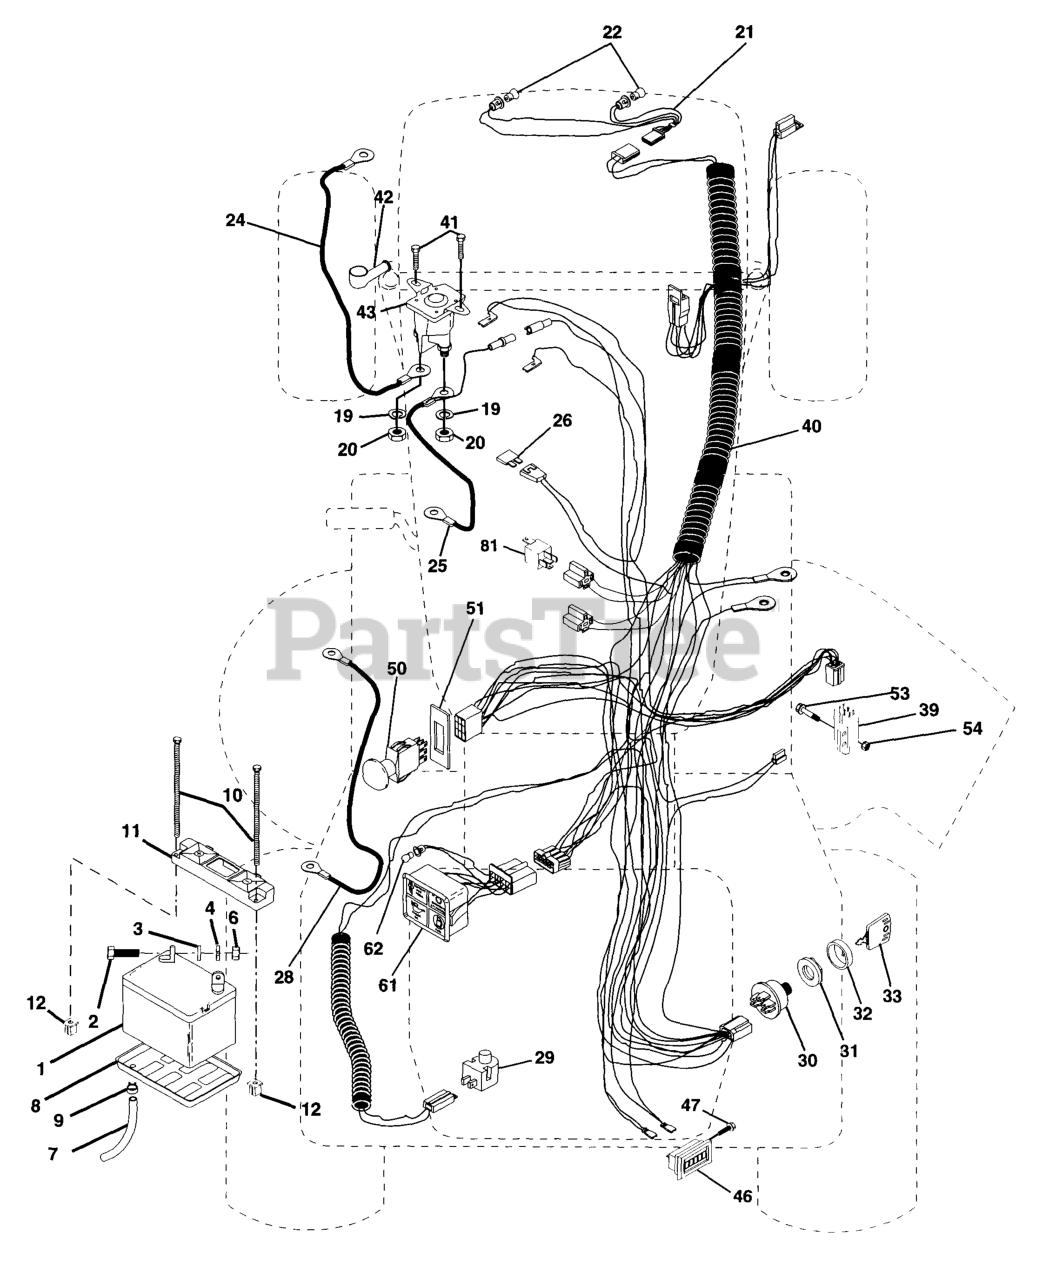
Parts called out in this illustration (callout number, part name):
1	BATTERY
2	BOLT.HEX.1/4.X.3/4.DICHROMATE
3	LOCKWASHER
4	WASHER
6	NUT
7	PLASTIC TUBE
8	BATTERY TRAY T
9	HOSE CLAMP T
10	BOLT 1/4-20 X 7.5
11	BATTERY HOLDDOWN FRONT MOUNT
12	NUT, PUSH NYLON 1/4" BATTERY
19	LOCKWASHER
20	NUT
21	HARNESS LIGHT SOCKET
24	CABLE, STARTER
25	CABLE, BATTERY
28	CABLE, GROUND
29	RP.SWITCH.PLUNGER.NC.GRAY
30	SWITCH.IGNITION.4.POSITION
31	NUT IGNITION
32	COVER SWITCH KEY
33	KEY.MOLDED.GENERIC
39	SWITCH INTERLOCKT
40	HARNESS IGN.
41	SCREW
42	TERMINAL COVER
43	SOLINOID
46	HOUR METER T
47	Screw #10-24 x 1/2
50	SWITCH PTO 3 PDT
51	FRAME RETAINING RING
53	SCREW **
54	Nut Keps #10-32
61	LIGHT PACKAGE
62	BULB LIGHT T
81	RELAY.ASSY.T
